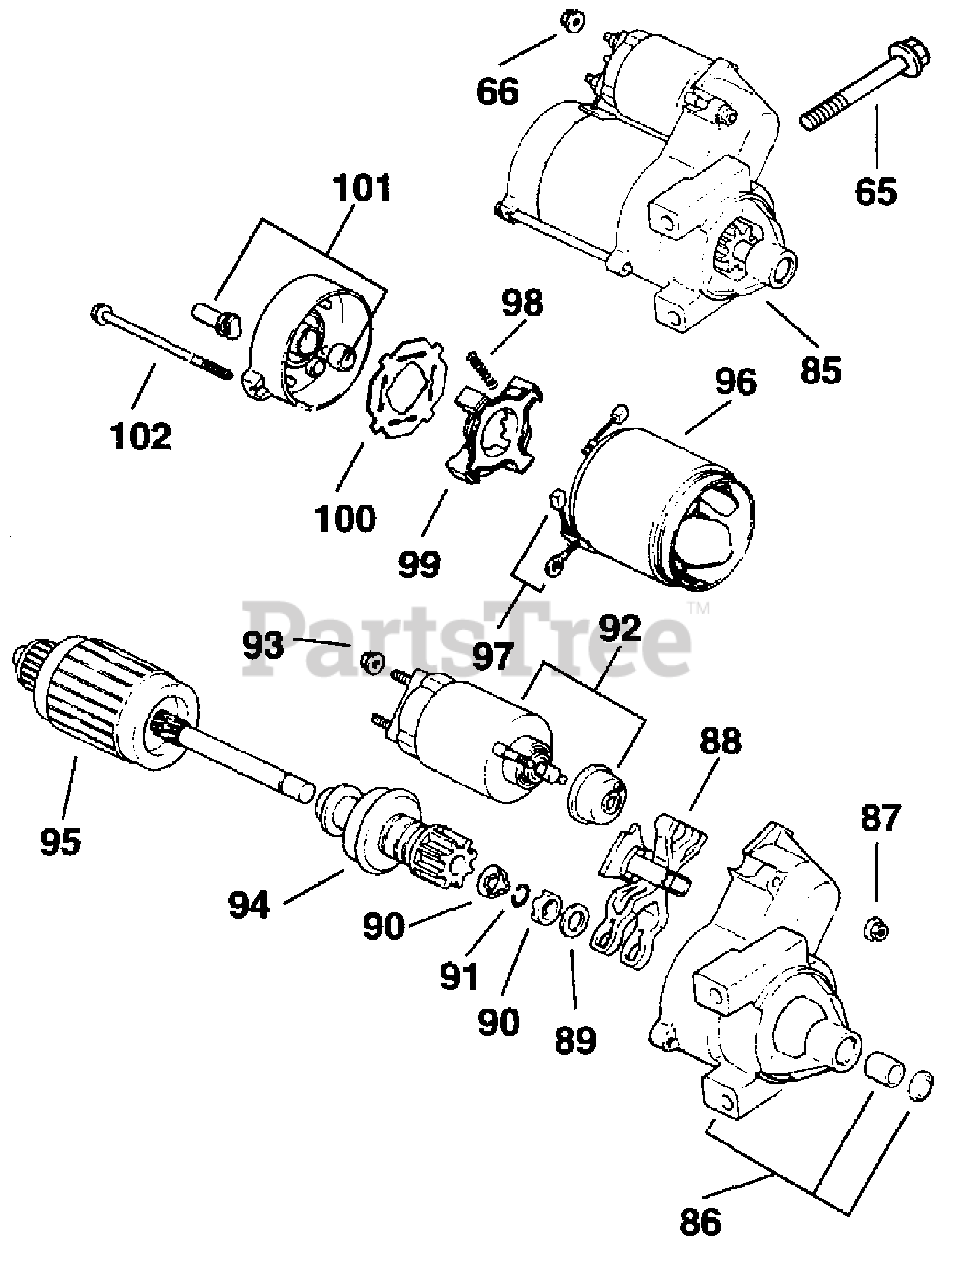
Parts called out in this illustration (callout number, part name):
65	Screw, hex. flange M8x1.25x80
66	NUT - USE M-841080
86	DRIVE, END CAP
87	NUT
88	LEVER, DRIVE
89	KIT - USE 24 755 84
90	KIT - USE 24 755 84
91	KIT - USE 24 755 84
92	SOLENOID
93	NUT
94	DRIVE PINION
95	ARMATURE - DISCONTINUED
96	FRAME W/BRUSHES - DISCONTINUED
97	BRUSH & SPRING KIT
98	SPRING, BRUSH
99	BRUSH HOLDER
100	INSULATOR
101	COMMUTATOR, END CAP - DISCONTINUED
102	THRU BOLT
5235701-S	Lubricant, Inertia Drive Starter (0.25 oz.)
